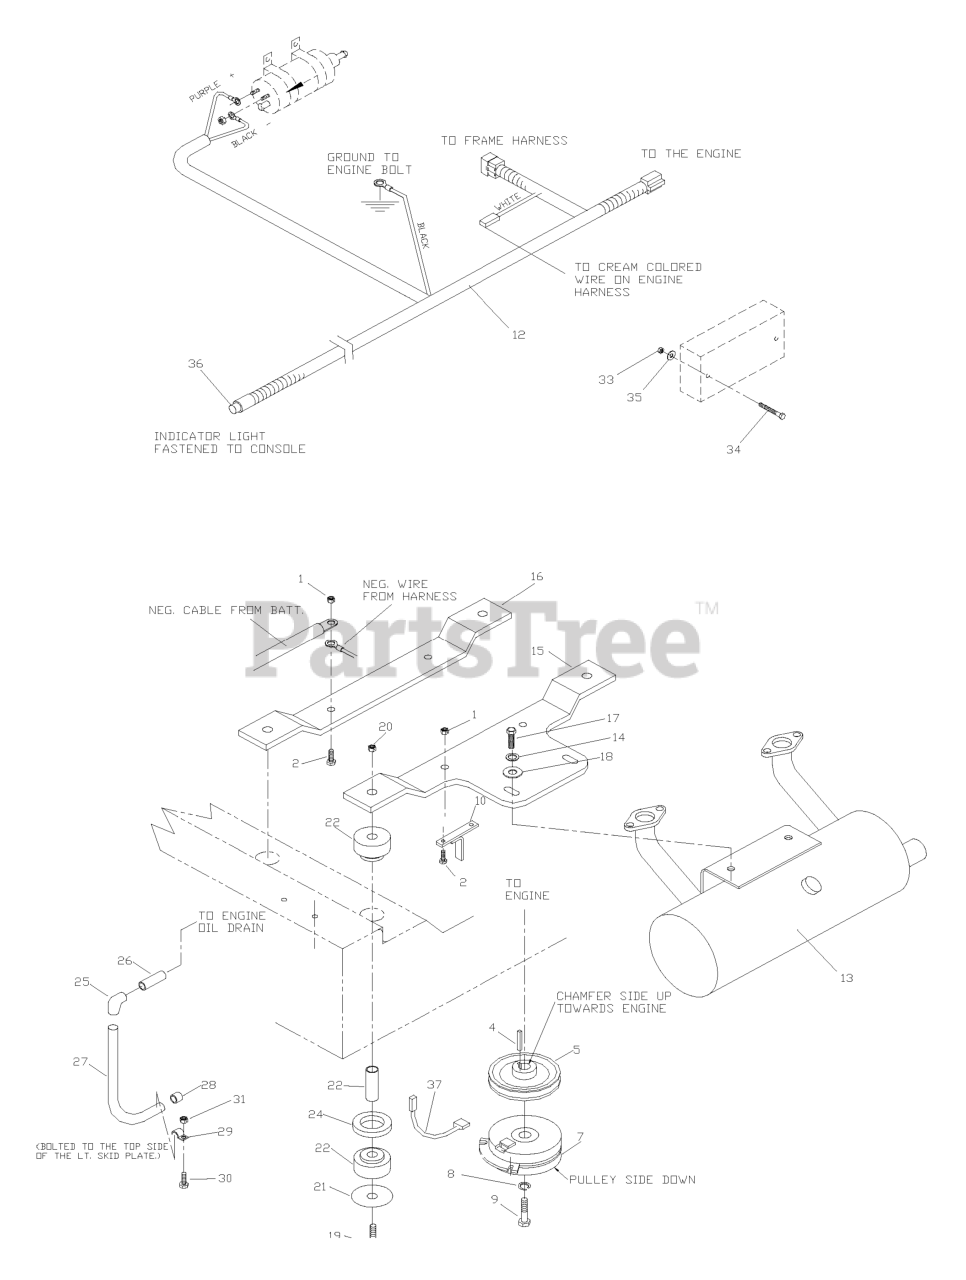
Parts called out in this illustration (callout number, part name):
1	NUT 5/16C CENTERLOCK
2	HCS 5/16C X 1 3/4
4	KEY 1/4" SQ X 1 7/8"
7	ELECTRIC CLUTCH W/CABLE
8	WASHER 7/16 LOCK
9	BOLT 7/16F X 2 1/2
10	CLUTCH TIE DOWN
12	WIRE HARNESS - EFI
13	MUFFLER EFI KOHLER GEN II
14	WASHER.LOCK.HVY.HLCL.SPR.5/16
15	REAR ENGINE MOUNT
16	ENGINE MOUNT
17	HCS 5/16C X 1
18	WASHER 5/16 FLAT
19	HCS 1/2C X 3 1/4
20	NUT 1/2-13 HEX NYLOC ZD
21	ISOLATOR WASHER
24	ISOLATOR SPACER
25	90 DEG.ELBOW 3/8NPT
26	PIPE 3/8 NPT 1-1/2
27	OIL DRAIN HOSE
30	HCS 1/4C X 3/4 HCS
31	NUT 1/4C CENTER LOCK
32	SCREW #10 X 1/2 SELF TAPPING
33	NUT 10-24 NYLOC
34	BOLT 10-24 X 2
35	WASHER #10
36	INDICATOR CARTRIDGE LAMP
37	CLUTCH HARNESS
